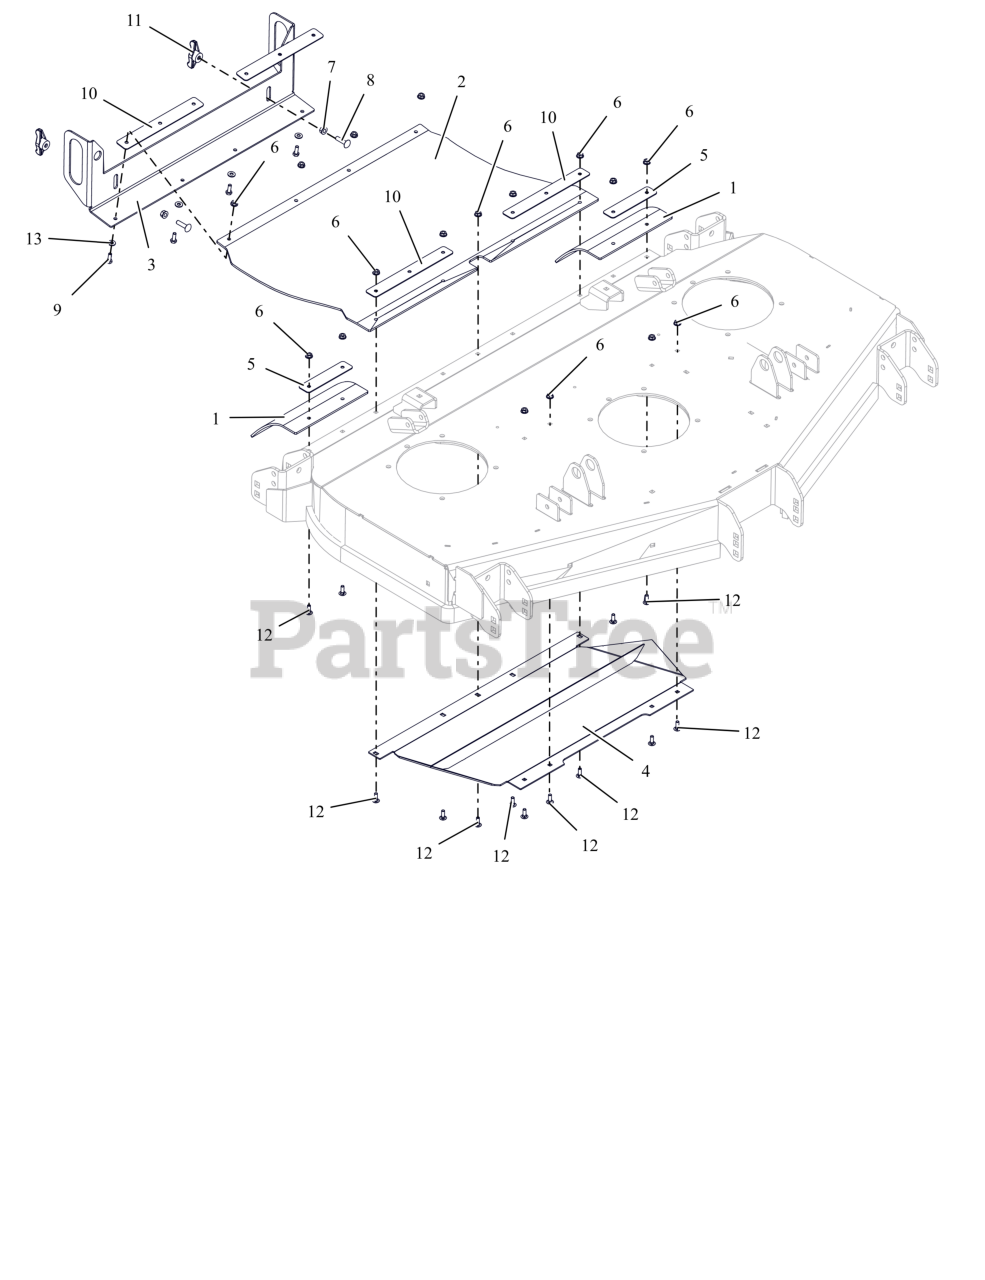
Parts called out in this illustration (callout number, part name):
1	FLAP, REAR DISCHARGE 52" TIRE
2	CHUTE, REAR DISCHARGE
3	HANDLE, CHUTE MOUNTING (ORANGE)
4	WLDMT, DEFLECTOR BAFFLE (ORANGE)
5	PLATE, 52" TIRE CHUTE MTG (BLACK)
6	NUT-LK-CTR-FLG .25-20 ZC120
7	NUT,LK-CTR-FLG .31-18 GF ZCC
8	BLT, RHSSN.31-18X1.25 G5 ZCC
9	BLT, HEX .25-20X.75 G5 ZCC
10	PLATE, CHUTE MTG (BLACK)
11	KNOB,WING .31-18 UNC NYL/TALC
12	BLT, RHSN .25-20X.750 G5 ZCC
13	WSHR,FLT .281X.625X.065 ZCC
